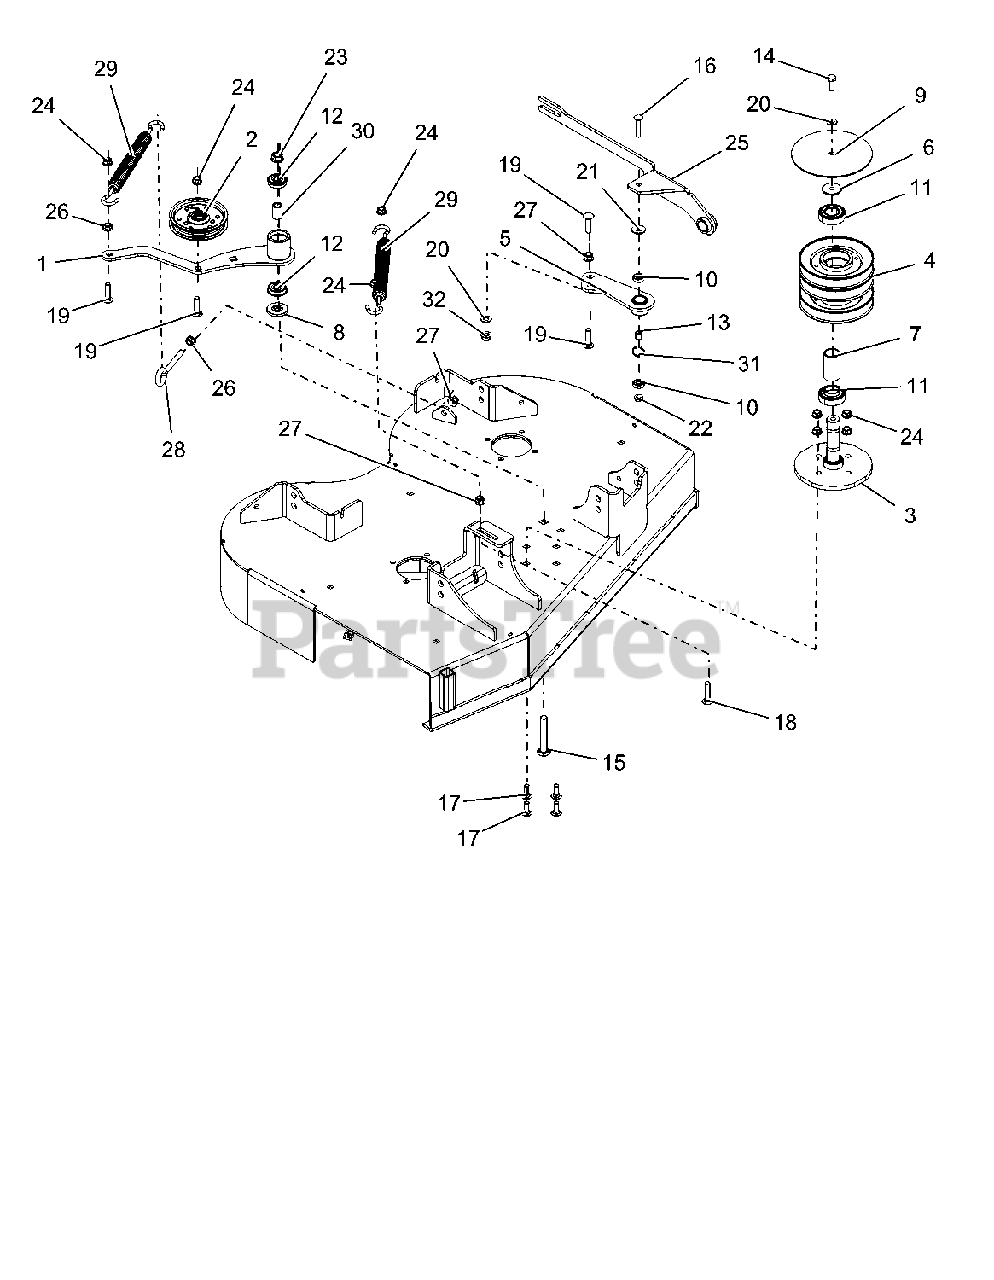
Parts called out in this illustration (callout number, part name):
1	WLDMT, IDLER ARM
2	ASM, 4" IDLER (.75 WIDE)
3	WLDMT, JACKSHAFT SHAFT
4	WLDMT, JACKSHAFT HOUSING
5	WLDMT, DECK IDLER
6	RETAINER, JACKSHAFT SPINDLE
7	SPCR, BEARING SPINDLE
8	SPACER, IDLER ARM
9	PLATE, JACKSHAFT COVER
10	BRG-BALL .315X.866X.276(608)
11	BEARING, RG 1.00X2.0467X.591
12	BRG-BALL .50X1.38X.438 SEALED
13	BSHG-SLV .330X.455X.550
14	@BLT-HEX .38-16X1.00 GR5 YWZC
15	BLT,RDHDSQSHNK.50-13X3.25 G5YZ
16	@BLT-RDHDSQNK .31-18X1.75 G5YZ
17	@BLT-RDHDSQNK .38-16X1.00 G5YZ
18	@BLT-RDHDSQNK .38-16X1.75 G5YZ
19	@BLT-RDHDSQNK .38-16X1.50 G5YZ
20	@WSHR-FL-STL.406X.812X.065 YWZ
21	@WSHR-FL-STL.531X1.06X.095YWZC
22	@NUT-LK-CTR-FLG .31-18 YZ GR F
23	NUT-LK-CTR-FLG .50-13 YWZC
24	NUT-LK-CTR-FLG .38-16 YWZC
25	WLDMT, PIVOTING IDLER
26	@NUT-SPNLK-FLG .375-16 YWZC
27	@NUT-LK-NYL-FLG .38-16 YWZC
28	BOLT,EYE .38-16X4.50,.75"EYE
29	SPRING, EXTENSION
30	SPACER .510 X .75 X 1.1485
31	RING, RETAINING 7/8" INT
32	@NUT-LK-NYL-FLG .38-16 YWZC
